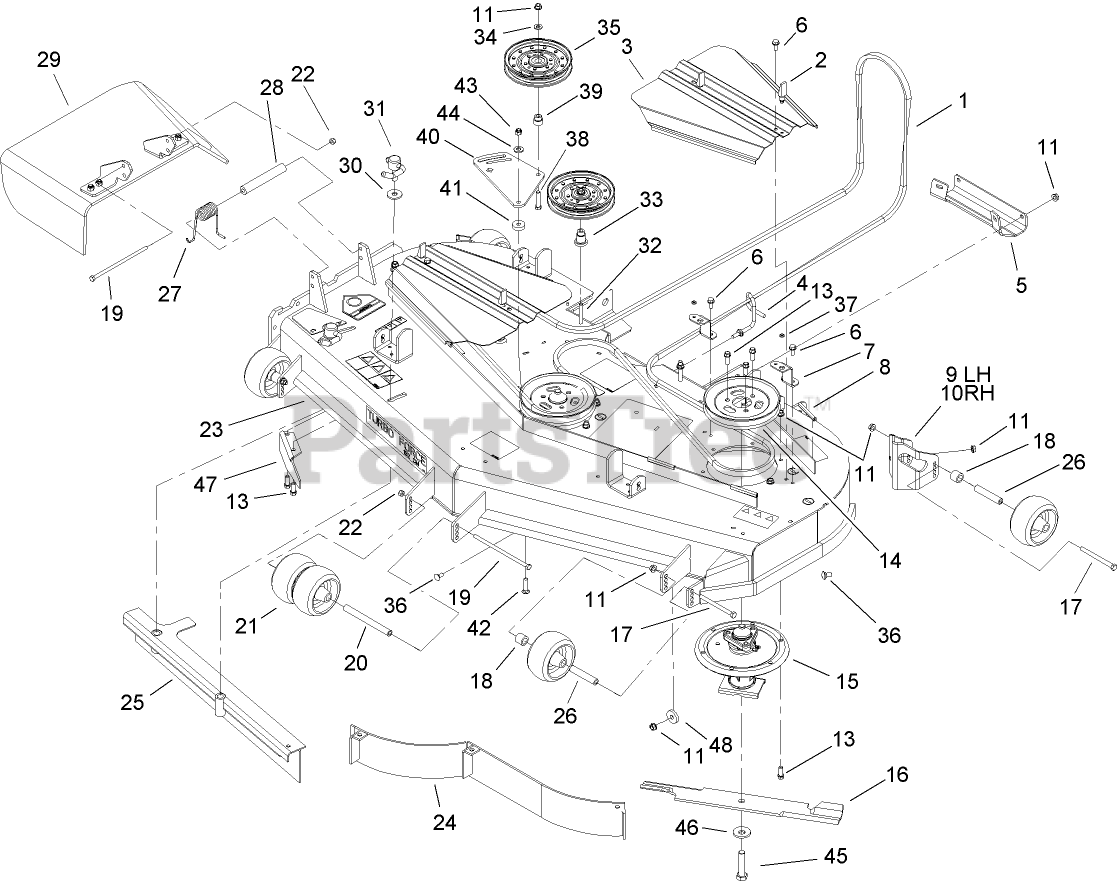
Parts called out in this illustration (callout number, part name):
2	LATCH-SWELL
3	Cover-Belt
4	GUIDE-BELT
5	Plate-Skid
6	SCREW-HWHTF
7	Bracket-Cover
8	STRIP-SEAL
9	MOUNT-WHEEL, LH
10	MOUNT-WHEEL, RH
11	NUT-HHF, WHIZ
13	SCREW-TAPTITE
14	Pulley
15	Spindle ASM
16	Blade-Rotary, High Flow
17	SCREW-HH
18	TUBE-SPACER
19	SCREW-HH
20	SPACER-WHEEL
21	ROLLER-SCALP, ANTI
22	NUT-LOCK, NI
23	DECK ASM
26	TUBE-SPANNER
27	SPRING-TORSION
28	SPACER
29	Rubber Deflector ASM
30	WASHER-PLASTIC
31	Lever ASM
32	SCREW-HH
33	MOUNT-PULLEY
34	WASHER-FLAT
35	Idler-Flat
36	SCREW-CARR
37	WASHER
38	SCREW-HH
39	BUSHING-IDLER
40	Plate-Idler
41	Spacer
42	SCREW-CARR
43	NUT-LOCK, NI
44	WASHER-BELLEVILLE
45	Screw-Cap
46	Washer-Blade Bolt, Heavy
47	BAFFLE-DISCHARGE
48	WASHER
99	BLADE-MID FLOW, 20.5 INCH
99	BLADE-LO FLOW, 20.5IN
99	BLADE-RECYCLER, 20.5 INCH
99	BLADE-ATOMIC, 20.5IN
